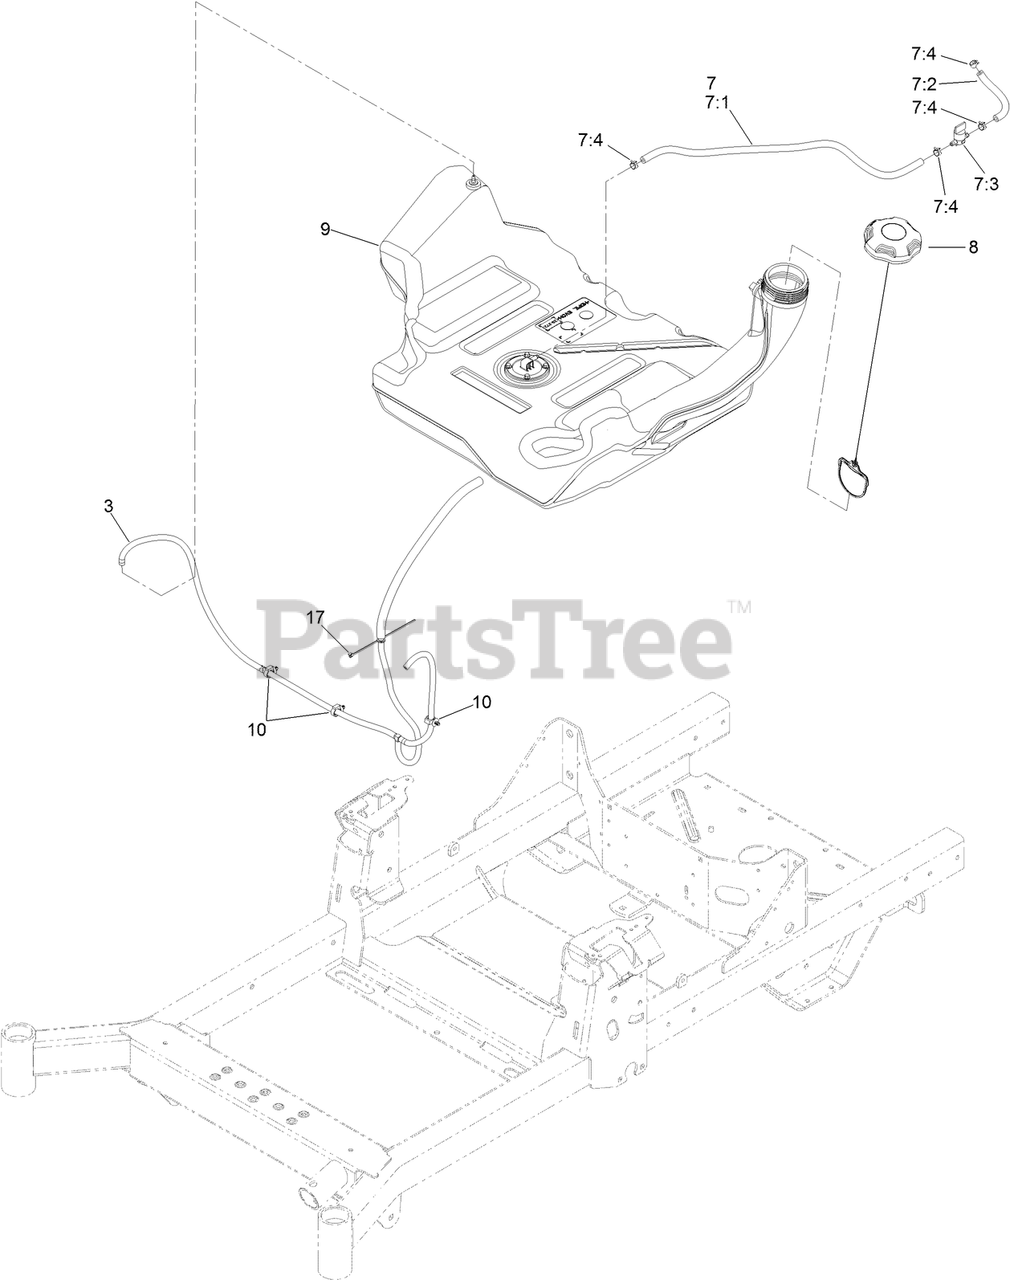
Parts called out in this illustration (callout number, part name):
3	VENT HOSE ASM
7	FUEL HOSE ASM
7:1	HOSE-FUEL
7:2	HOSE-FUEL
7:3	VALVE-FUEL
7:4	CLAMP-HOSE
9	TANK-FUEL
17	TIE-CABLE
